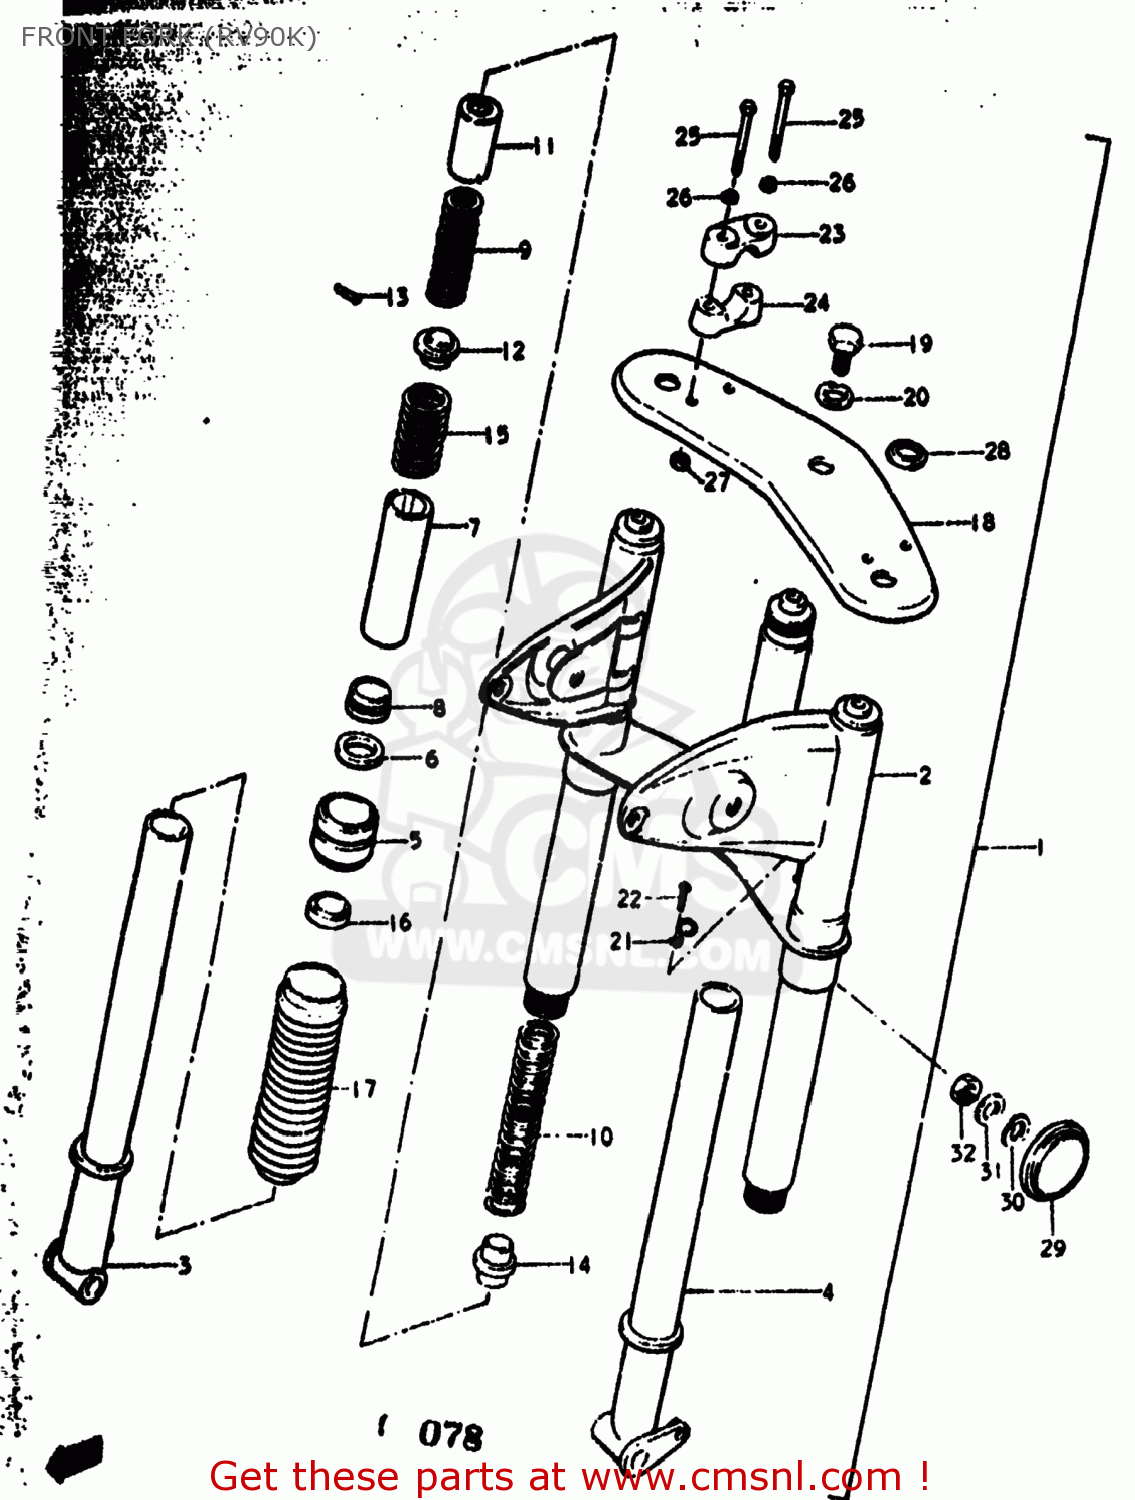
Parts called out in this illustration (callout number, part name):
1	DAMPER SET
2	STEM,STEERING
3	TUBE,OUTER,RIGHT
4	TUBE,OUTER,LEFT
5	SPRING,FRONT FORK
6	OIL SEAL (22.2X30X5)
7	BUSHING,GUIDE
8	VALVE,OIL LOCK
9	SPRING,FRONT FORK
10	SPRING,FRONT FORK
12	GUIDE,SPRING
13	PIN,SPRING(4.5X22)
14	GUIDE,SPRING WASHER
15	SPRING,REBOUND
16	CUSHION
17	BOOT,FRONT FORK COVER
18	HEAD,STEERING STEM
19	BOLT
21	GUIDE,CABLE
22	SCREW
23	HOLDER,HANDLEBAR
24	HOLDER,HANDLEBAR
25	BOLT
26	LOCK WASHER
27	NUT
28	WASHER
29	REFLECTOR ASSY, FRONT TO 35950-31010
30	LOCK WASHER
31	WASHER
32	NUT
